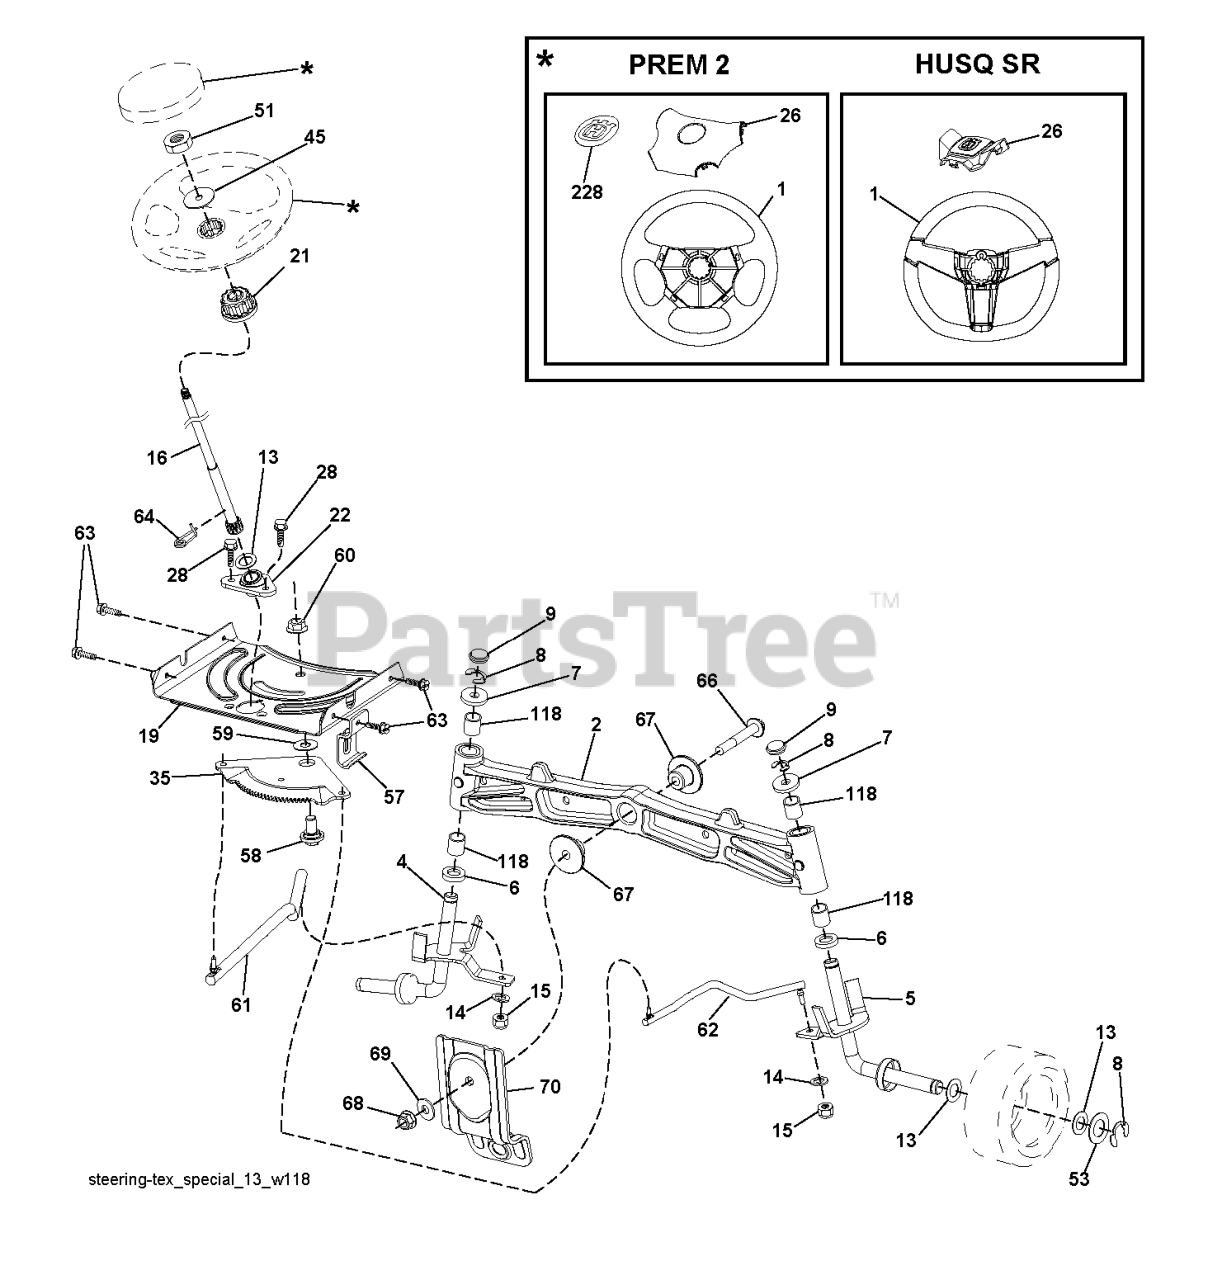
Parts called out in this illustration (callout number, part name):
1	RP WHEEL.STEER.HUSQ.PREM.OVMLD
2	AXLE.SVC.ASM CAST IRON.TEX
4	SPINDLE.WELDED.LH.16"TEX
5	SPINDLE.WELDED.RH.16"TEX
6	THRUST WASHER
9	CAP.SPINDLE.BLACK
14	WASHER, LOCK 3/8
15	NUT CROWNLOCK 3/8-24
16	SHAFT.STEER.STEALTH.DD
19	PLATE.STEER.DDL.NLT/NG
21	ADAPTER, WHEEL STNG..
22	BUSHING.ASM.STEERING.A
26	RP INSERT.CAP.WHL.STRG.HUSQ.
28	SCREW, 3/8-16X3/4
35	GEAR.SECTOR.PLATE.DDL.
45	WASHER 9/16"ID, 2 3/8"OD
51	NUT.HEX.1/2-20
53	WASHER.HARDENED
57	BRKT.UPSTOP.GT/LT.TEX
58	BOLT.SHOULDER.SECTOR.P
59	WASHER.THURST.SECTOR.S
60	NUT FLANGE LOCK 5/8-11
61	DRAGLINK.LH.BALLSTUD.D
62	DRAGLINK.RH.BALLSTUD.D
63	SCREW
64	RETAINER.CLIP.SPRING.S
66	BOLT HEX FGHD 7/16-14 X 3 SERR
67	BUSHING.PM.FRONT AXLE
68	NUT.LOCK.FLANGE.7/16
69	WASHER.1.5X.505X.118
70	BRKT.DECK.SUSPENSION.F
118	BUSHING, AXLE CAST
